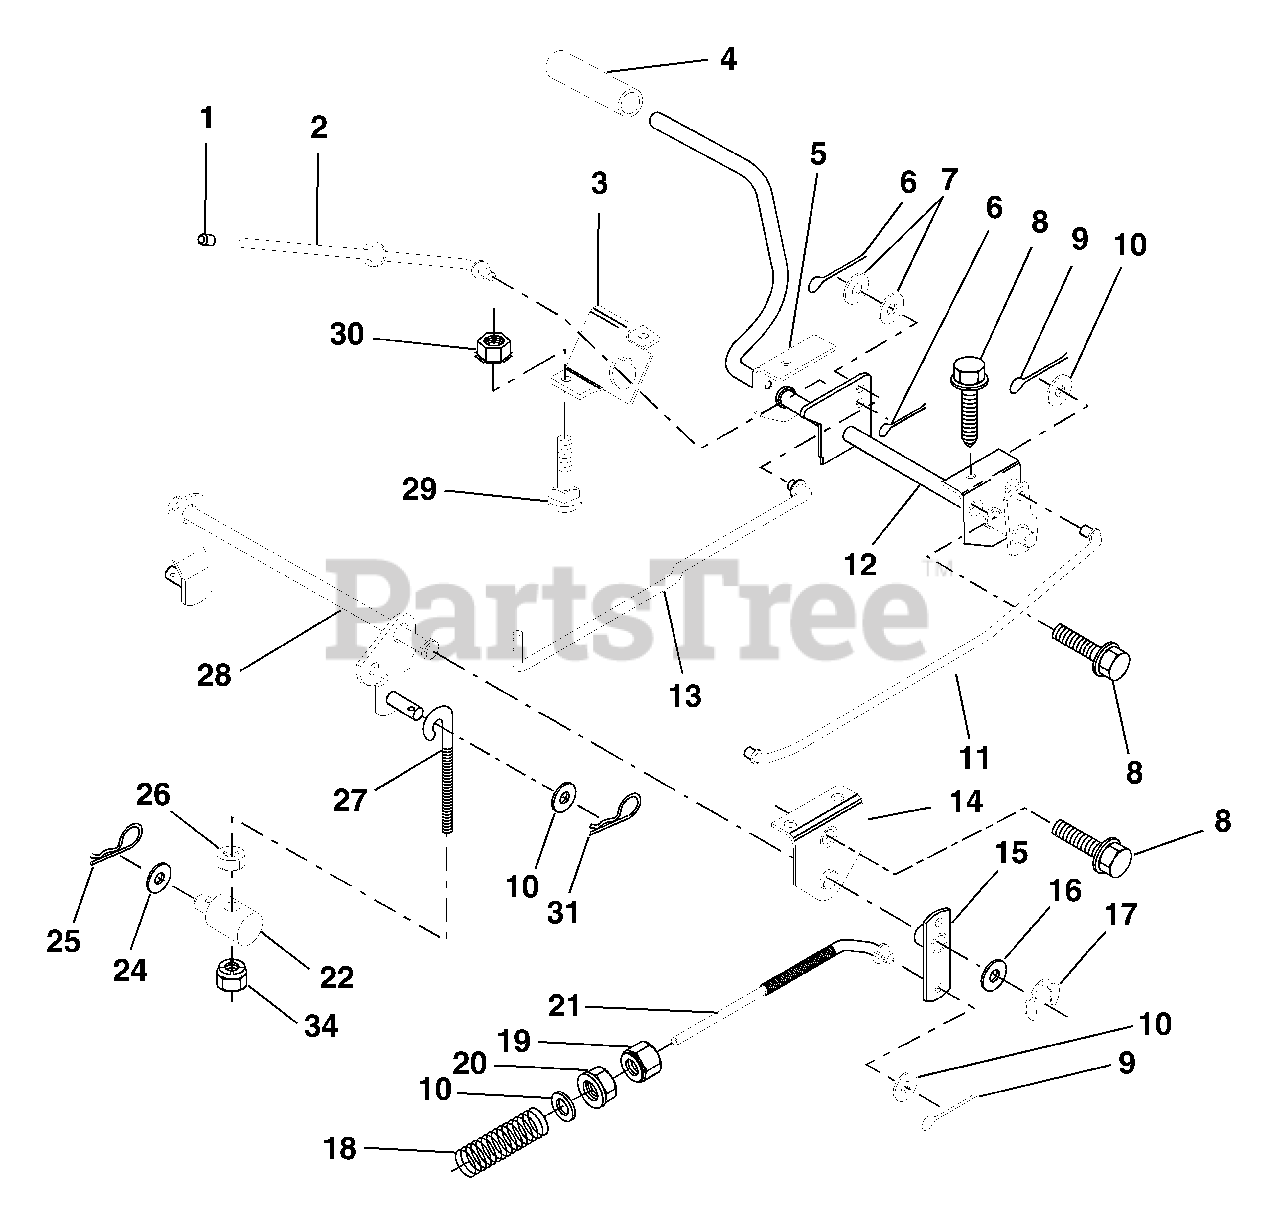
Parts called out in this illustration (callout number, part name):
1	Cap, Plunger
2	Rod, Parking Brake
3	Bracket, Parking Brake
4	Cover, Pedal
5	Bracket, Clutch/Brake Pedal, L.H.
6	Pin, Cotter 3/32 x 3/4
7	Washer 13/32 x 5/8 x 16 Ga.
8	Screw, Hex, Thd. Roll. 5/16-18 x 1/2
9	Pin, Cotter 1/8 x 3/4
10	Washer 13/32 x 13/16 x 16 Ga.
11	Rod, Brake Front
12	Assembly, Clutch/Brake Pedal
13	Rod, Clutch
14	Bracket, Lift, Shaft
15	Assembly, Brake, Pivot, Arm
16	Washer 25/32 x 1-1/8 x 16 Ga.
17	Ring, Klip
18	Spring, Brake Rod
19	Nut, Hex, Jam 3/8-16 UNC
20	Nut, Lock, Hex w/Ins 3/8-16 Unc
21	Rod, Rear Brake
22	Trunnion, Lift
24	Washer 13/32 x 1-1/4 x 12 Ga.
25	Spring, Retainer
26	Nut, Centerlock 3/8-16 UNC
27	Link, Threaded
28	Assembly, Rear Mower Lift
29	Bolt, Carriage 5/16-18 UNC x 3/4
30	Nut, Keps 5/16-16 UNC
31	Retainer Spring
34	Locknut, Crownlock 3/8-16
